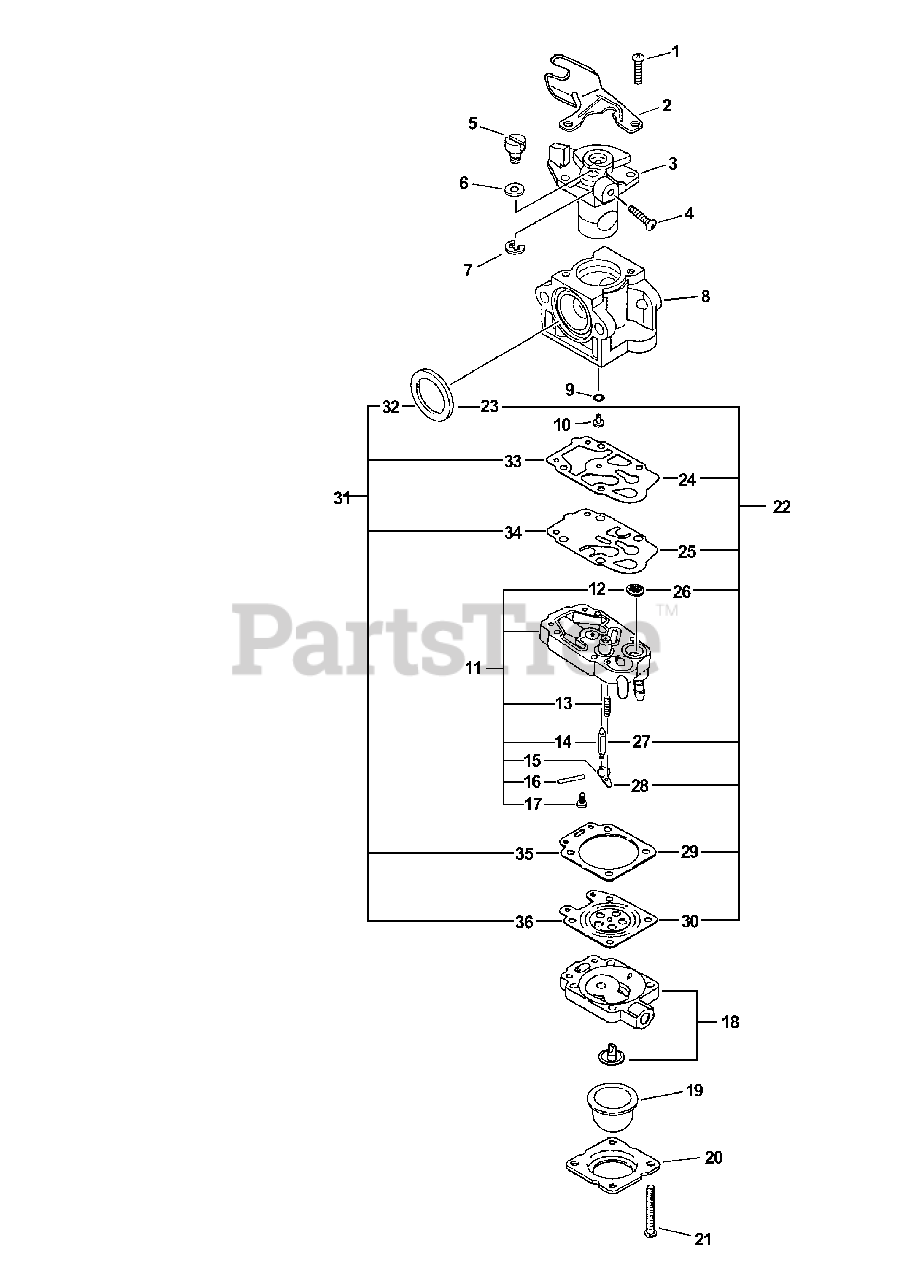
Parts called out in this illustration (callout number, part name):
2	BRACKET, CABLE
3	THROTTLE VALVE ASSY
4	SCREW, IDLE ADJUST
7	RING, RETAINING
8	BODY, CARBURETOR
11	BASE, PURGE
12	STRAINER
13	SPRING, METERING LEVER
14	VALVE, INLET NEEDLE
15	LEVER, METERING
16	PIN, METERING LEVER
17	SCREW, METERING LEVER PIN
18	PURGE BASE ASSY
19	BULB, PURGE
20	RETAINER, PURGE BULB
21	SCREW, PUMP COVER
22	REPAIR KIT
23	SEAL
24	GASKET, PUMP
25	DIAPHRAGM, PUMP
26	STRAINER
27	VALVE, INLET NEEDLE
28	LEVER, METERING
29	GASKET, DIAPHRAGM
30	DIAPHRAGM, METERING
31	DIAPHRAGM/GASKET KIT
32	SEAL
33	GASKET, PUMP
34	DIAPHRAGM, PUMP
35	GASKET, DIAPHRAGM
36	DIAPHRAGM, METERING
